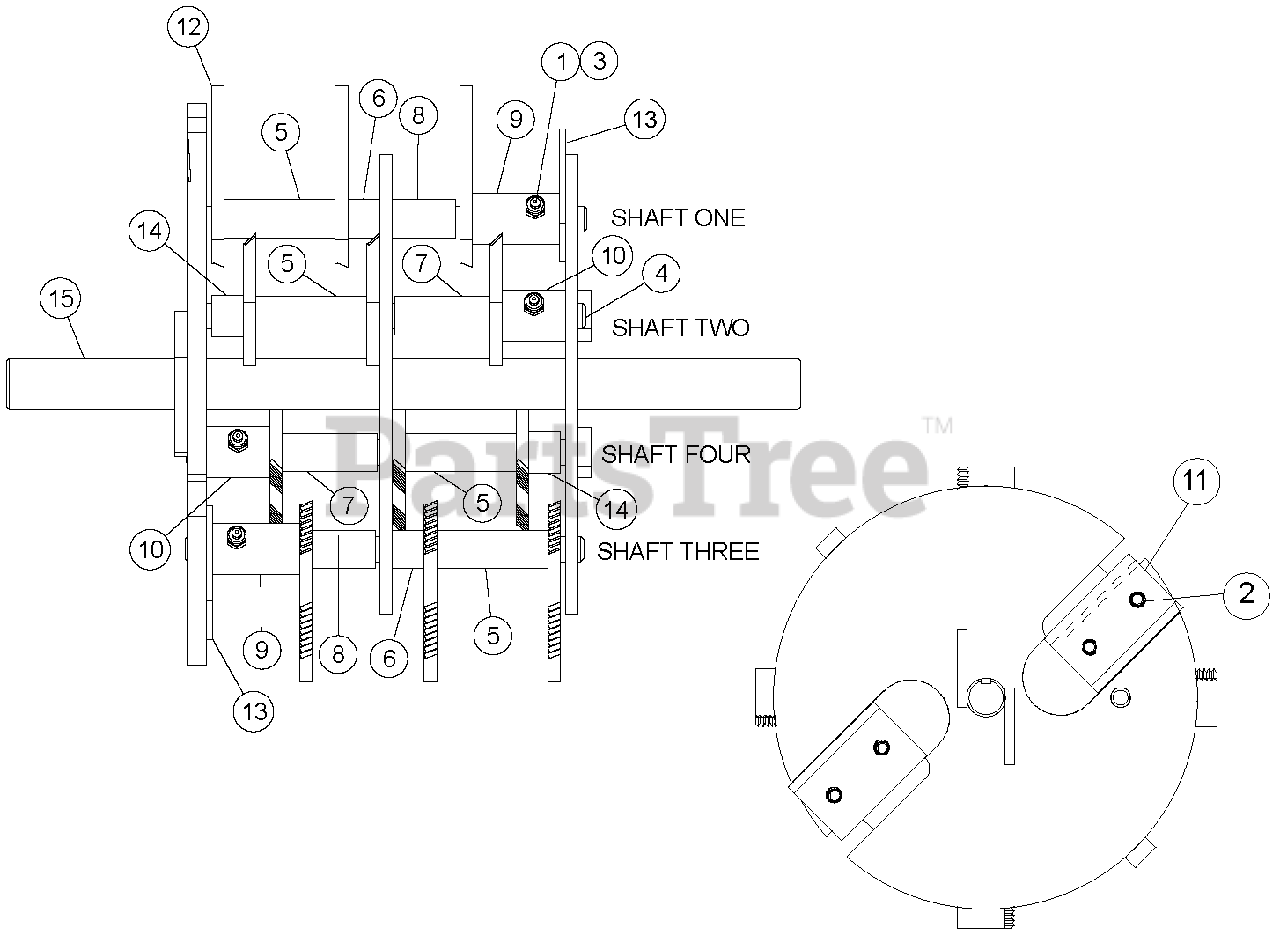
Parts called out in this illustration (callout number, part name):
1	NUT, #10 X 24 NYLOCK
2	BOLT, 5/16 X 5/8 GR 8
3	SCREW, 10-24 X 1-3/8 IN. SKT HD CAP
4	SHAFT KNIFE, LONG
5	SPACER, 0.75 X 2.170
6	SPACER, .75 X .62
7	SPACER, 0.75 X 1.850
8	SPACER, 0.75 X 1.24
9	SPACER, 1.0 X 1.70 WITH HOLE
10	SPACER, 1.0 X 1.24 WITH HOLE
11	BLADE, TWO EDGE CHIPPER (FOR SERVICE ORDER KIT # 738, TWO EDGE TOOL STEEL BLADE)
11	KIT, TWO EDGE BLADE
12	SHREDDING KNIFE, RECTANGULAR
13	KNIFE, ROTOR BALANCE
14	SPACER, 0.81 X 0.62
15	WELDMENT, WIDE ROTOR (FOR ASSY. 70970)
15	WELDMENT, BALANCED RENTAL ROTOR (FOR ASSY. 74209-00)
